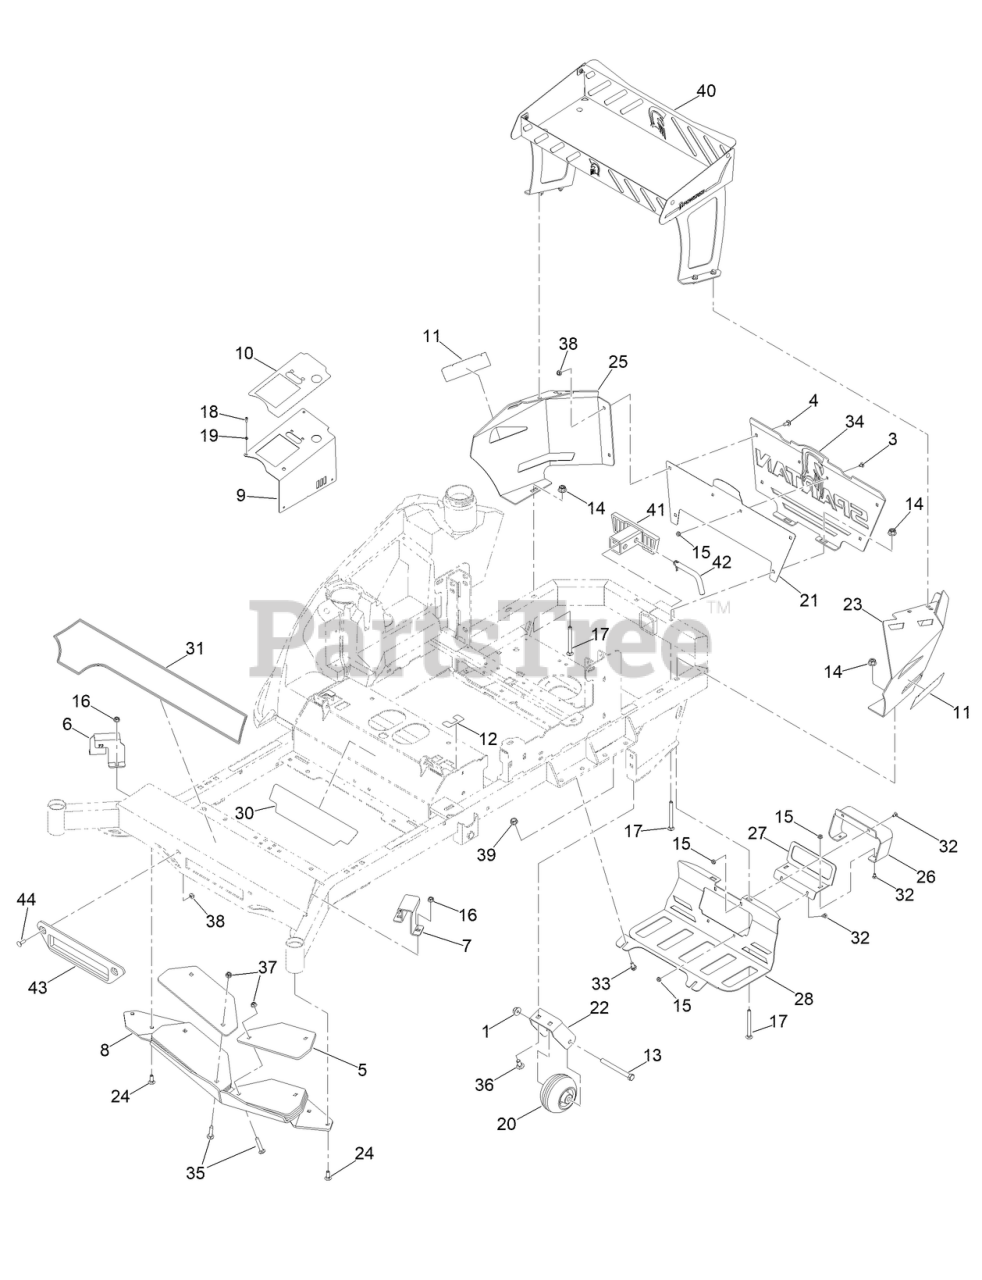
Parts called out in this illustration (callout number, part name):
1	NUT-LOCK
3	SCREW-CARR
4	BOLT-CARR
5	2023 COUNTER WEIGHT PLATE
6	2023 COUNTER WEIGHT TOP MOUNT BRK 72
7	2023 COUNTER WEIGHT TOP MOUNT BRK 73
8	2023 COUNTER WEIGHT RT/SRT BOTTOM MOUNT
9	BRACKET-CONSOLE [BLK-TXT]
10	DECAL-CONSOLE
11	DECAL-COWLING
12	DECAL-MOTION CONTROL
13	SCREW-HH
14	3/8-16 NYLON INSERT FLANGE L/NUT YZ
15	1/4-20 HEX FLANGE NUT W/SERR ZINC
17	3/8-16 X 4 CARRIAGE BOLT ZINC
18	10-24 X 1/2 SOCKET C/S 18-8 SS
19	#10 SPLIT LOCKWASHER 18-8 SS
20	MWR ANTI-SCALP WHL W/O GREASE FITTING
21	KGZ ENGN COWLING CTR BACKER PLATE PAINT
22	MWR STABILIZER MTG BRKT BLACK
23	KGZ ENGN COWLING LT PAINTED
24	3/8-16 X 1 CARRIAGE BOLT YZ GR.8
25	KGZ ENGN COWLING RT PAINTED
26	EXHAUST TIP GUARD [ORANGE]
27	DUAL EXHAUST TIP BOTTOM BRKT BLACK
28	MUFFLER GUARD [BLK-TXT]
30	DECAL-KGZ-XD GT TRAC MODEL
31	DECAL-FLOORBOARD
32	SCREW-CARR
33	BOLT-HWH
34	KGZ ENGN COWLING CNTR PAINTED
35	SCREW-CARR
36	SCREW-CARR
37	3/8-16 HEX FLANGE NUT W/SERR ZINC YELLOW
39	NUT-HF
40	SPOILER BASKET, BLACK
41	MWR RR RECEIVER NYLON BUMPER
42	HITCH PIN SHORT FOR INTMDR RR HITCH
43	MWR FT NYLON BUMPER
44	BOLT-CARR
